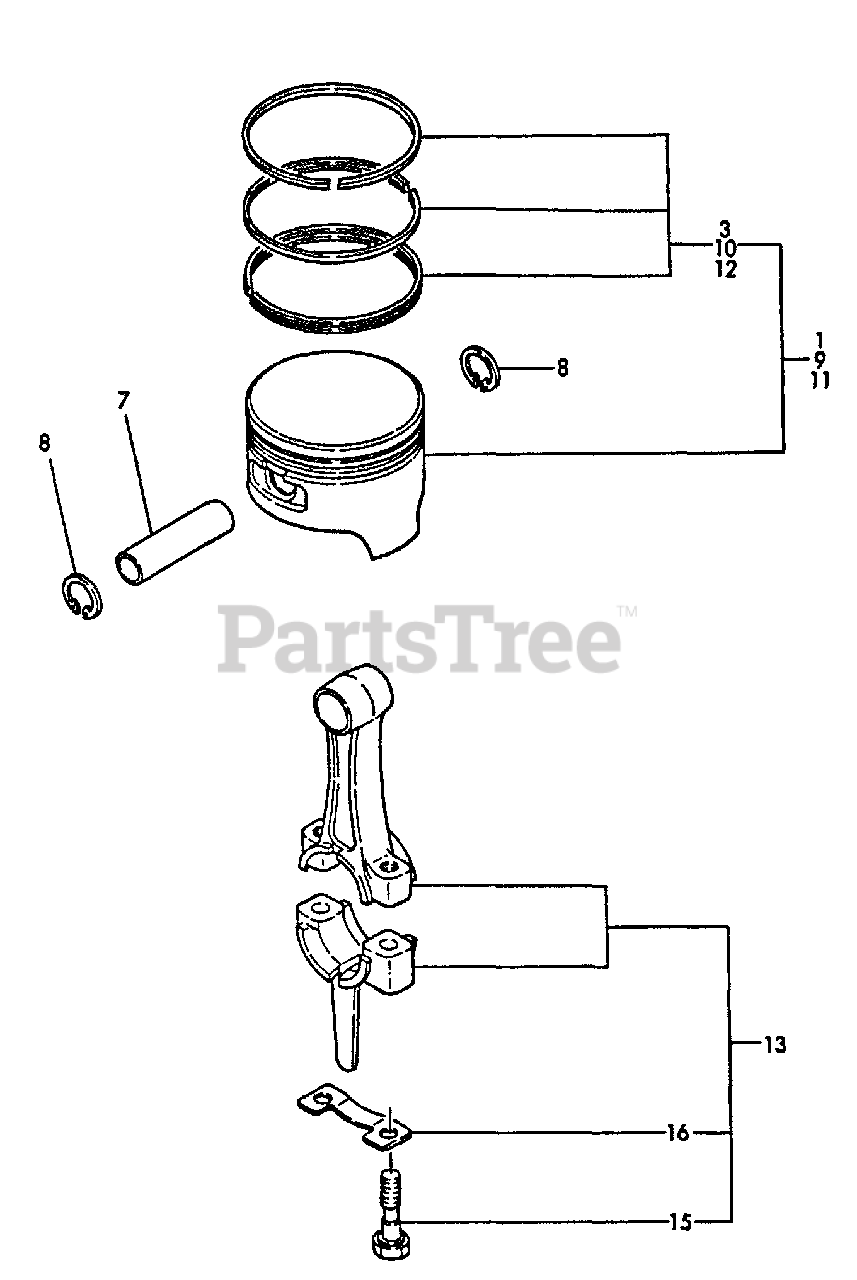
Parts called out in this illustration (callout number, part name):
1	PISTON ASSY
3	RING, PISTON
7	PIN, PISTON
8	RING, RETAINING - 16
9	PISTON ASSY O.S.=0.25
10	RING, PISTON
11	PISTON ASSY O.S.=0.5
12	RING, PISTON
13	CONNECTING ROD ASSY
15	BOLT, ROD
16	WASHER
